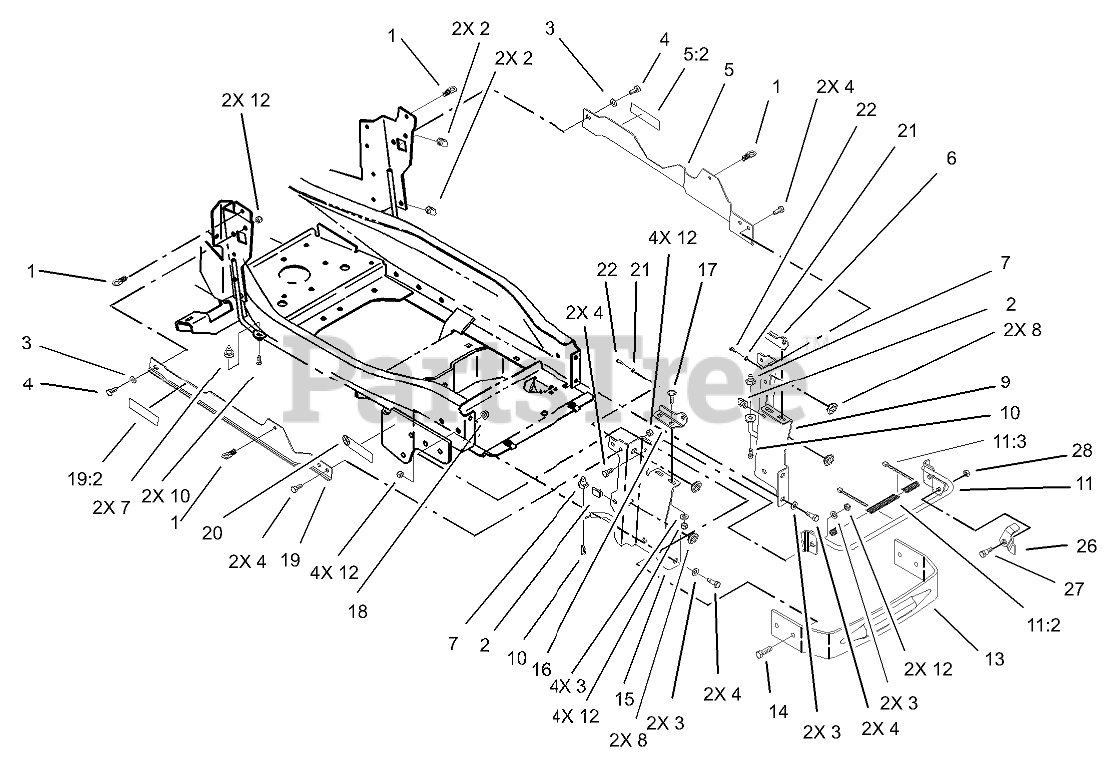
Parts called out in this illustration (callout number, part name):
1	LATCH ASM
3	WASHER-PLAIN
4	SCREW-HH
5	SUPPORT ASM
5:2	DECAL - WARNING
6	BRACKET-HINGE, LOWER LH
7	MOUNT-SIDEPANEL
8	GROMMET
9	SUPPORT-HOOD, LH
10	SCREW-PLASTITE
11	SUPPORT-HOOD
11:2	COVER-BRACE
11:3	TIE-CABLE
12	NUT-LOCK, NI
13	BUMPER-FRAME
14	SCREW-HH
15	SUPPORT-HOOD, RH
16	BRACKET-HINGE, LOWER RH
17	SCREW-CARR
18	NUT-LOCK, NI
19	SUPPORT ASM
19:2	DECAL - WARNING
20	DECAL-ATTACH A-MATIC
21	WASHER-FLAT
22	SCREW-THD FORM, HWH
26	LEVER-PROP, HOOD
27	BOLT-SHOULDER
28	NUT-LOCK, NI
